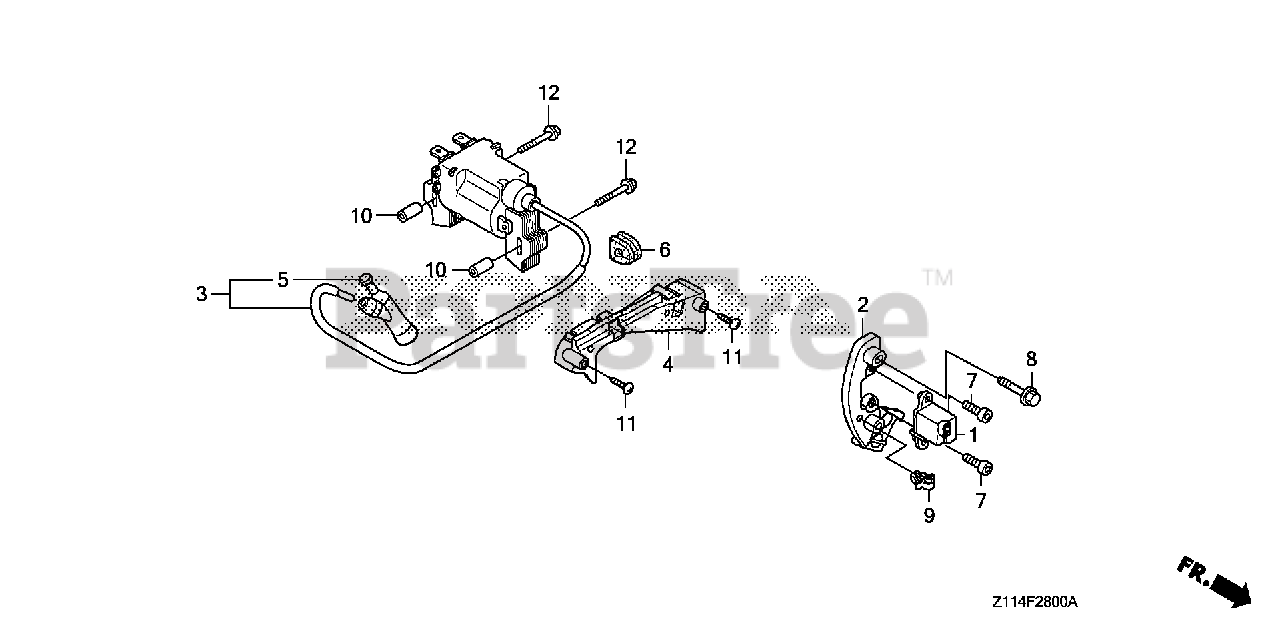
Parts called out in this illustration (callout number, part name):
1	GENERATOR ASSY., PULSE (TEC)
2	BRACKET, PULSER COIL
3	COIL ASSY., IGNITION
4	CLAMP, IGNITION WIRE
5	CAP ASSY., NOISE SUPPRESSOR (TEC)
6	GROMMET, WIRE
7	BOLT, SOCKET (5X14)
8	BOLT, FLANGE (6X25) Use up to Engine SN 2056819.
9	CLIP, ENGINE STOP SWITCH CORD
10	COLLAR (6.6X13.8X14.5)
11	SCREW, TAPPING (5X16) (PO)
12	BOLT, FLANGE (6X45)
